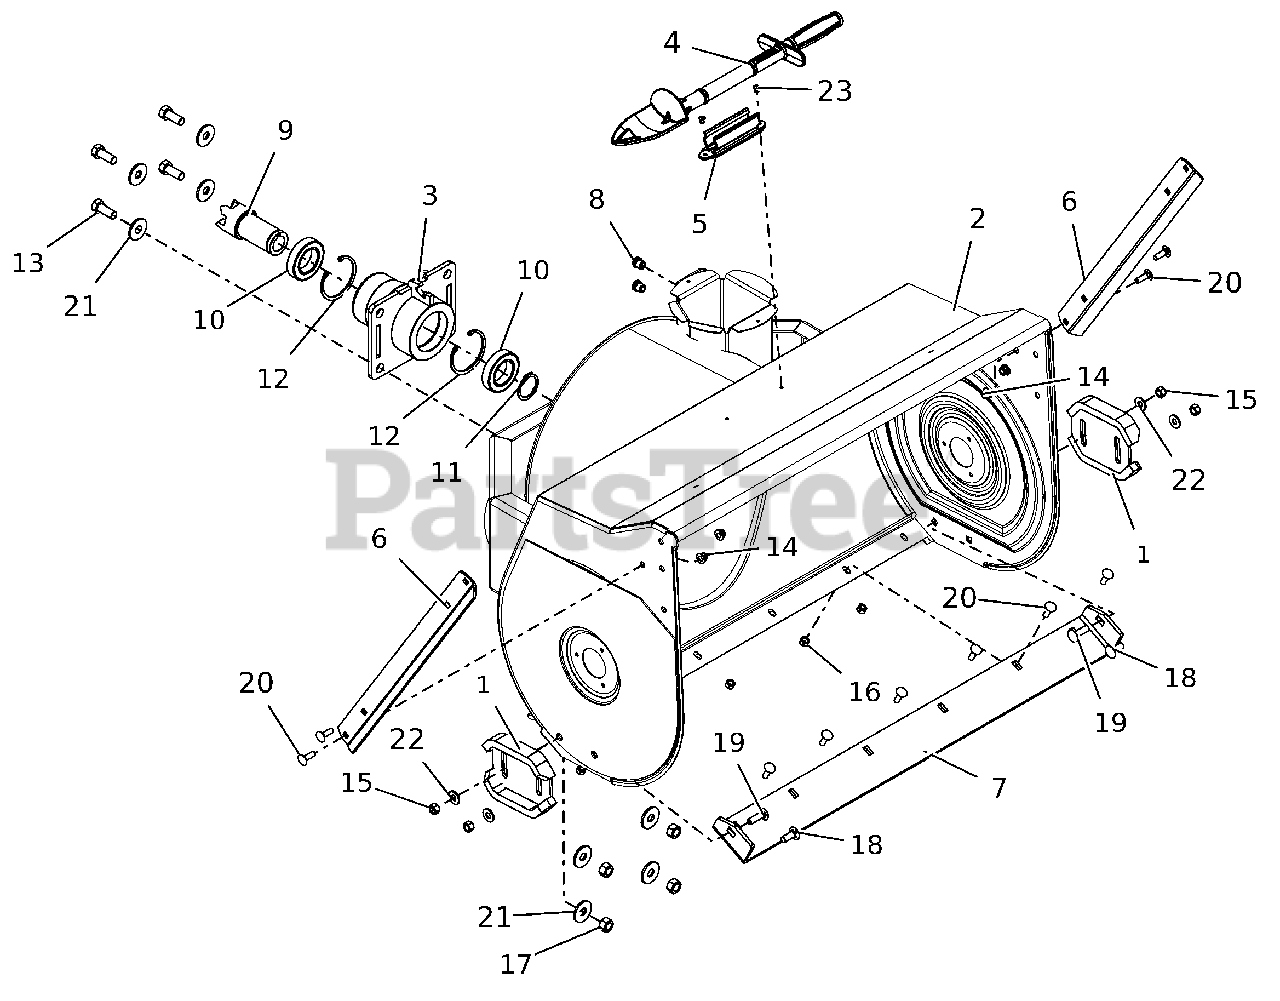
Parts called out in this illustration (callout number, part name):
1	RUNNER, SKID SHOE
2	HOUSING, BLOWER-32" W/DECALS
3	WLDMT. CONNECTOR
4	DEVICE, SNOW CLEAN OUT
5	MOUNT, SNOW CLEAN OUT
6	CUTTER BAR - G
7	BLADE, 32" SNOW SCRAPER
8	NUT,THD,INSERT .38-16 ZC120
9	COUPLING, TOOTH DRIVE
10	BRG-BALL 1.575X2.677X.590 2RLD
11	RING, RETAINING-EXT 40MMX1.75
12	RING, RETAINING-INTERNAL
13	BLT,HEX .50-13X1.25 G5 ZCC
14	NUT,NYL-FLG .31-18 GF ZCC
15	NUT-LK-CTR .38-16 ZC120
16	NUT,LK-CTR .31-18 GA ZCC
17	NUT,LK-CTR .50-13 GA ZCC
18	BLT,RHSSN .38-16X1.00 G5 ZCC
19	BLT,RHSSN .38-16X1.25 G5 ZCC
20	BLT,RHSN .31-18X1.00 G5 ZCC
21	WSHR-FL-STL.511X1.44X.125ZC120
22	WSHR,FLT .375X.875X.083 ZCC
23	RVT-POP .187 YZ
